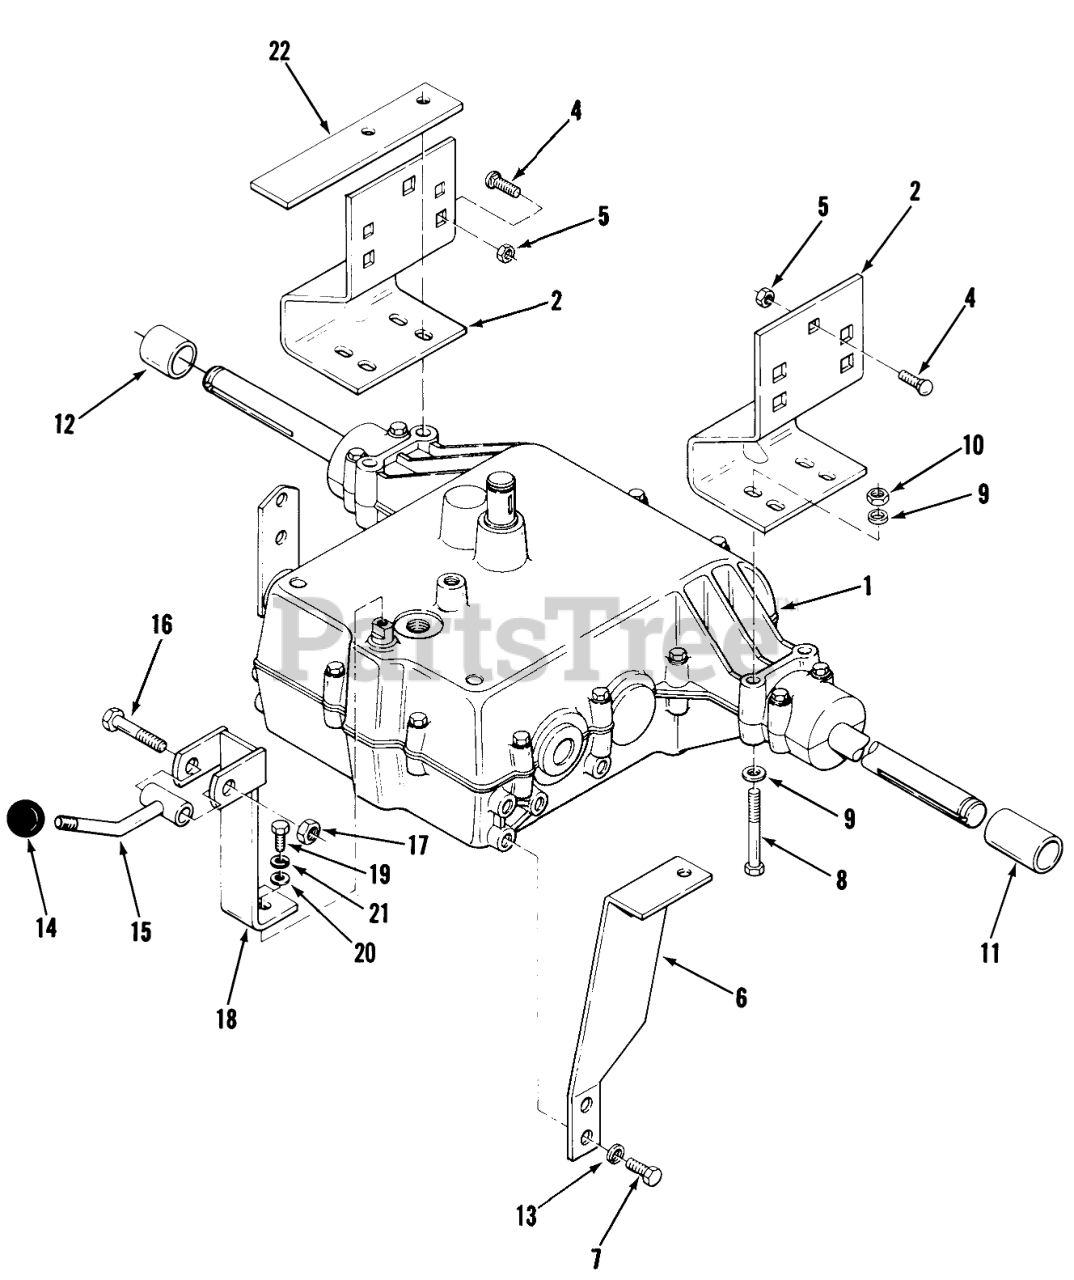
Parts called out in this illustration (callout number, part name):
1	Transmission-Peerless Model 822
1	Transmission-Peerless Model 801-002
2	BRKT-TRANS MOUNT R
2	Bracket-Rear Axle RH
2	Rear Axle Bracket LH 211-5
4	CARRIAGE BOLT -4
5	Nut
6	TORQUE STRAP
6	Torque Strap
7	Screw
8	HHCS
9	WASHER 5/16 SAE
10	Nut
11	SPACER-AXLE LH
12	SPACER-AXLE RH
13	Lockwasher
15	ASSY-UPPER SHIFT ROD
16	Bolt
17	Nut
18	ASSY LEVER R
19	Bolt 1/4-28 X 7/8
20	WASHER
21	Washer
22	Brake Stop Bar
